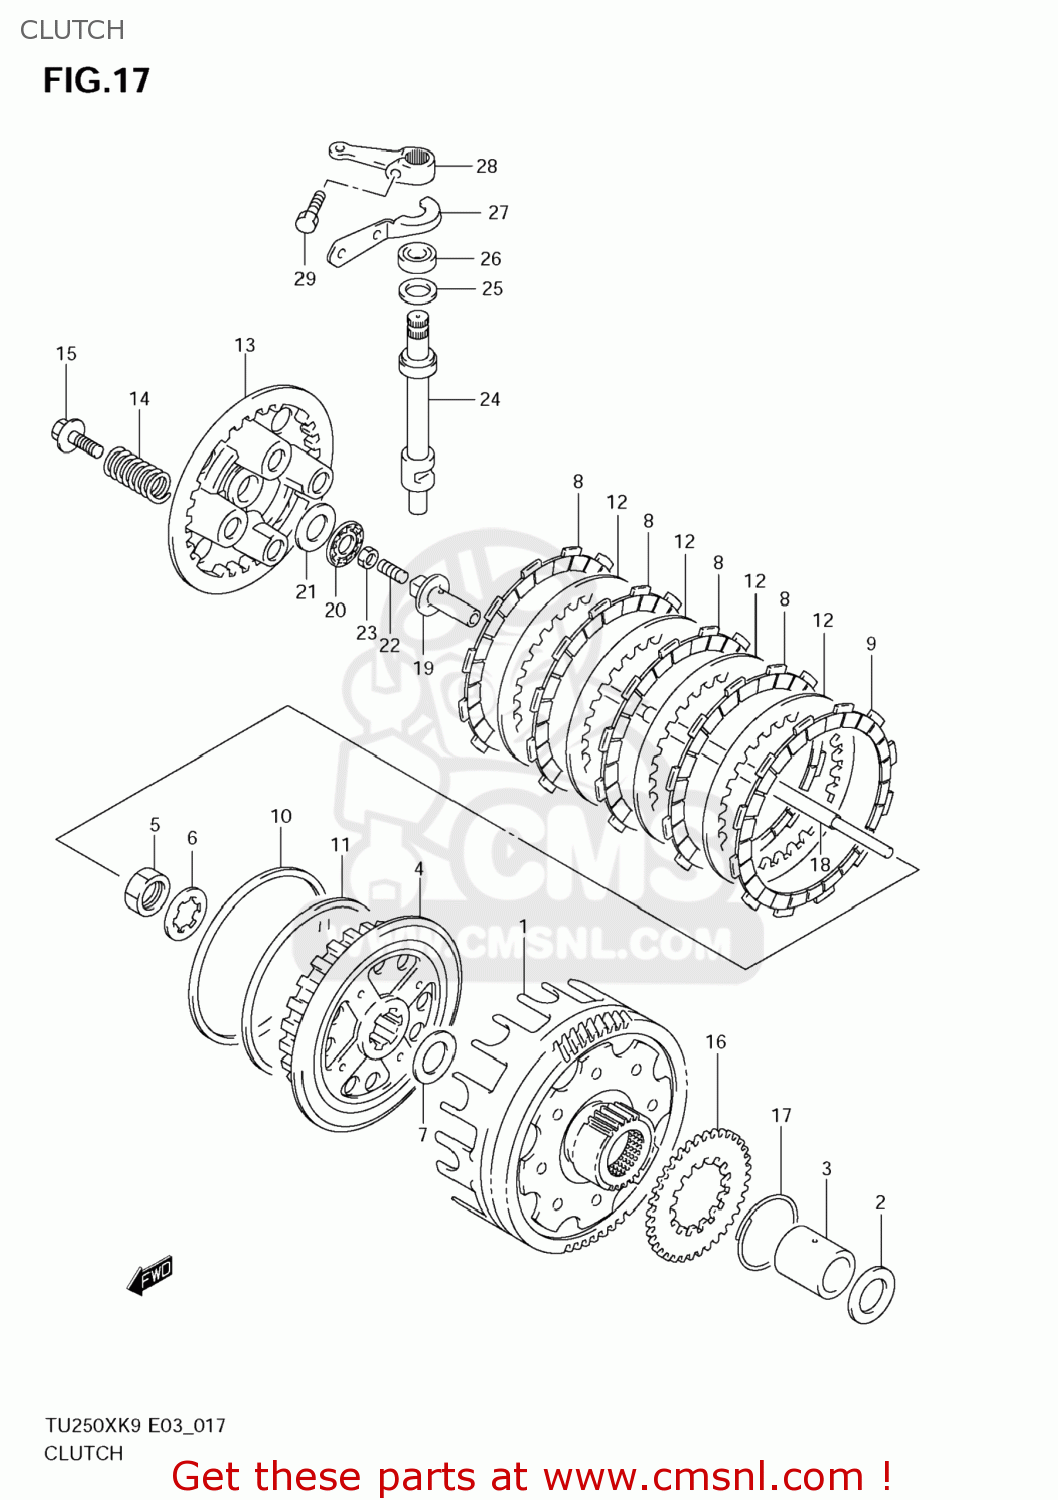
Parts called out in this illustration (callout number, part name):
1	GEAR ASSY,PRI DRIVEN
2	WASHER
3	SPACER(22X28X37.5)
4	HUB,CLUTCH SLEEVE
5	NUT
6	WASHER,LOCK
7	WASHER
8	PLATE,CLUTCH DRIVE (NAS)
9	PLATE,CLUTCH DRIVE(T:3.5) (NAS)
10	SEAT,WAVE WASHER(T:1.4)
11	WASHER
12	PLATE,CLUTCH DRIVEN(T:1.6) (NAS)
13	DISC,CLUTCH PRESSURE
14	SPRING,CLUTCH
15	BOLT(6X20)
16	GEAR,ENG OIL PUMP(NT:38)
17	CIRCLIP
18	ROD,CLUTCH PUSH
19	PIECE,CLUTCH PUSH
20	BEARING(15X28X2)
21	WASHER(15.5X28X1)
22	SCREW(6X25)
23	NUT
24	CAMSHAFT,CLUTCH RELEASE
25	WASHER(14.5X22X1)
26	OIL SEAL
27	PLATE,CLUTCH RRS CAMSHAFT SEAL
28	ARM,CLUTCH RELEASE
29	BOLT
